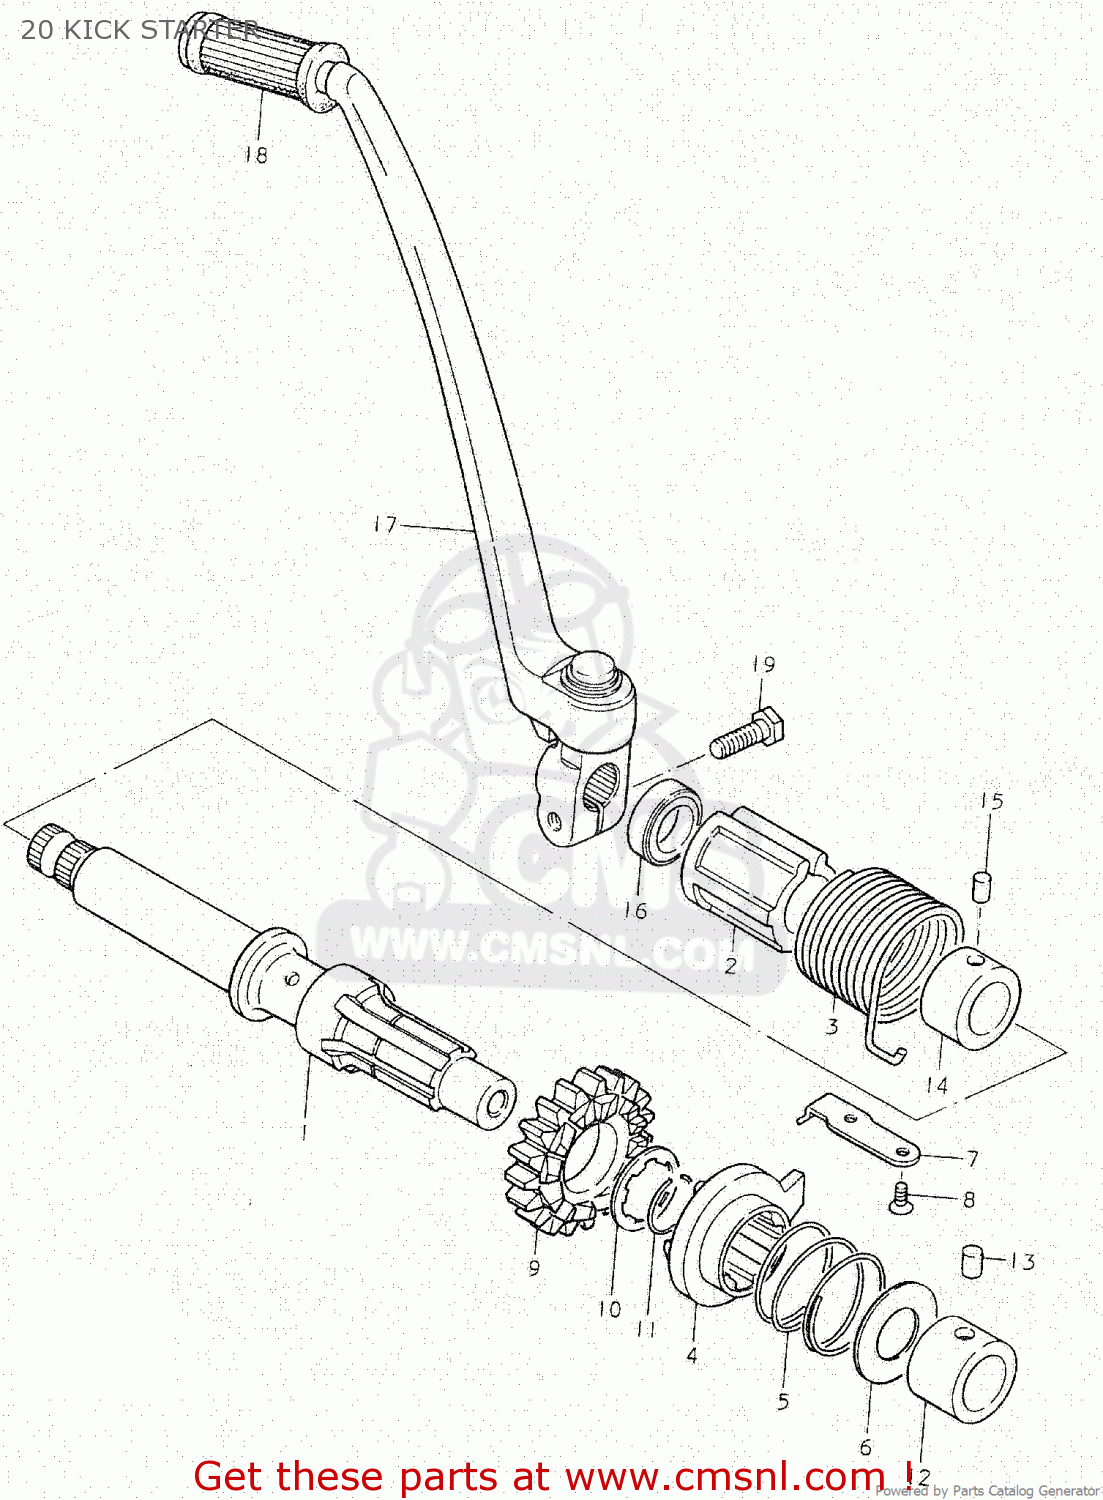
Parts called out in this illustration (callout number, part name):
1	SHAFT,KICK STARTER
2	GUIDE,KICK SHAFT SPRING
3	SPRING
4	STARTER,KICK
5	SPRING
6	WASHER
7	GUIDE,STARTING SPRING
8	SCREW
9	GEAR,KICK STARTER DRIVE
10	WASHER,LOCK
11	CIRCLIP
12	BUSHING
13	PIN
14	BUSHING
15	PIN
16	SEAL,OIL(20X27X5)
17	LEVER ASSEMBLY,KICK STARTER
18	RUBBER,KICK STARTER PEDAL
19	BOLT
